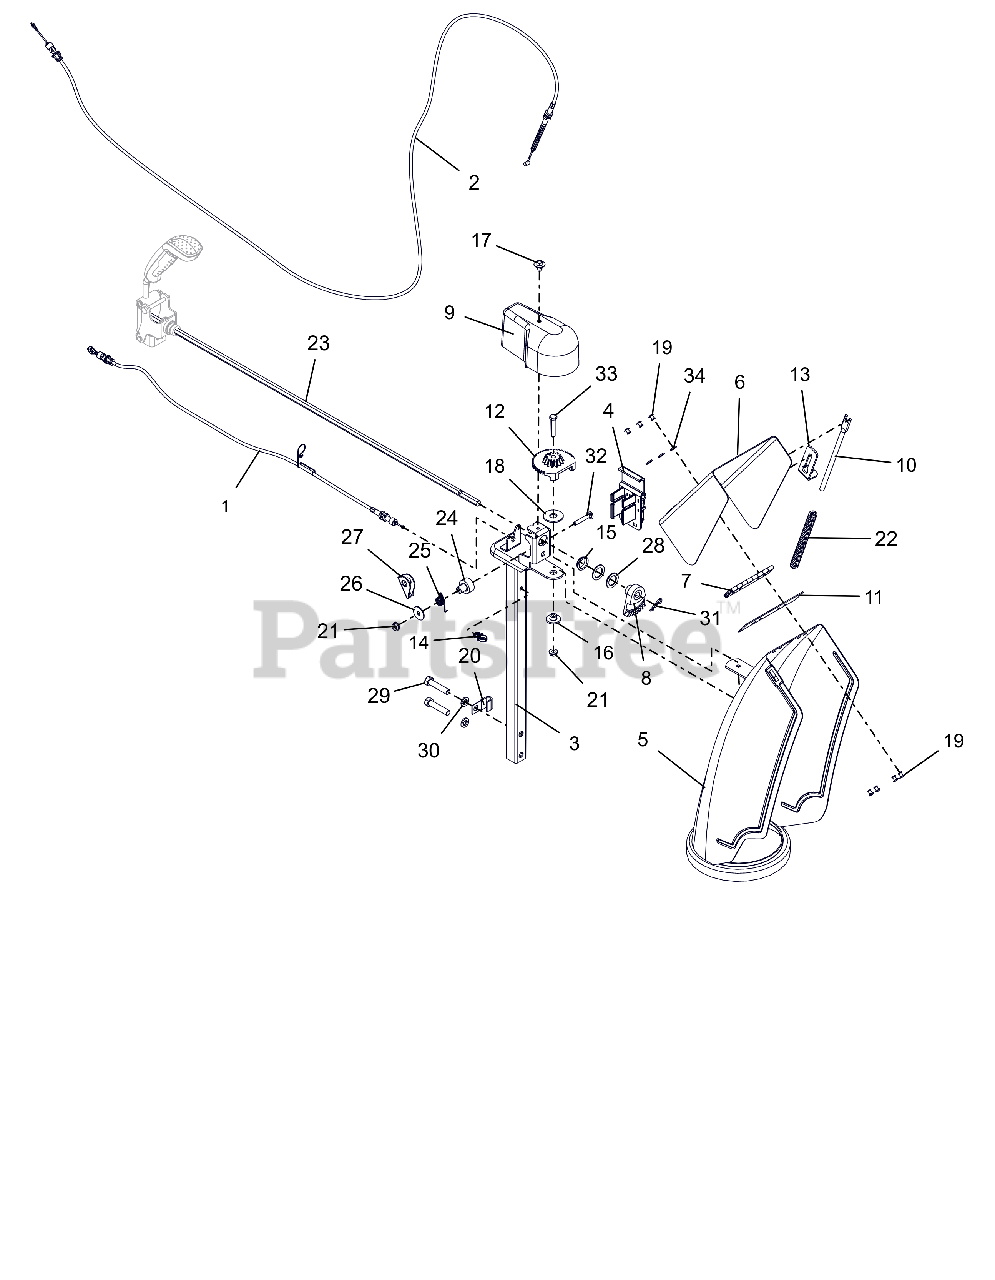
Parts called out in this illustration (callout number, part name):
1	CABLE, CHUTE LOCK, PRO
2	CABLE, DEFLECTOR - DELUXE
3	PEDESTAL, CHUTE - QUICK STICK
4	HOLDER W LARGE SHEAR BOLT /NUT
5	CHUTE,DISCHARGE,NOTCHED,QT
6	CAP, LARGE REMOTE W/DECAL
8	GEAR, CHUTE-ACTUATION
9	COVER, CHUTE GEAR
10	ROD, DEFLECTOR CAP
11	CAP SEAL 5.50
12	GEAR, CHUTE
13	BRACKET, ANCHOR-CHUTE CABLE
14	CLIP, CABLE GUIDE
15	BUSHING, POLYLINER-.75 SNAPIN
16	BSHG-FLG .265X.477X.375X1.00
17	SCR, TAP .25-20X.50 LG HWH ZCC
18	WSHR-FLT-NYL .515X1.375X.093
19	RVT, POP .1875 ZCC
20	J-CLAMP
21	NUT-LK-CTR-FLG .25-20 ZC120
22	SG-COMP .08X.40X6.50 14#/IN
23	ROD, HEX - CHUTE ROTATION
24	BUSHING, LOCK ARM
25	SG-TORS
26	WSHR,FLT .281X1.000X.063 ZCC
27	ARM, LOCKING
28	WSHR, FLT .754X1.125X.062 ZCC
29	BLT, HEX .38-16X1.75 G5 ZCC
30	WSHR,LK-REG .375X.094 ZCC
31	PIN, HAIR #213 .08X1.19 ZCC
32	BLT, RHSN .25-20X1.50 G5 ZCC
33	BLT, HEX .25-20X1.50 G5 ZCC
34	WSHR,FLT .196X.500X.066 ZCC
